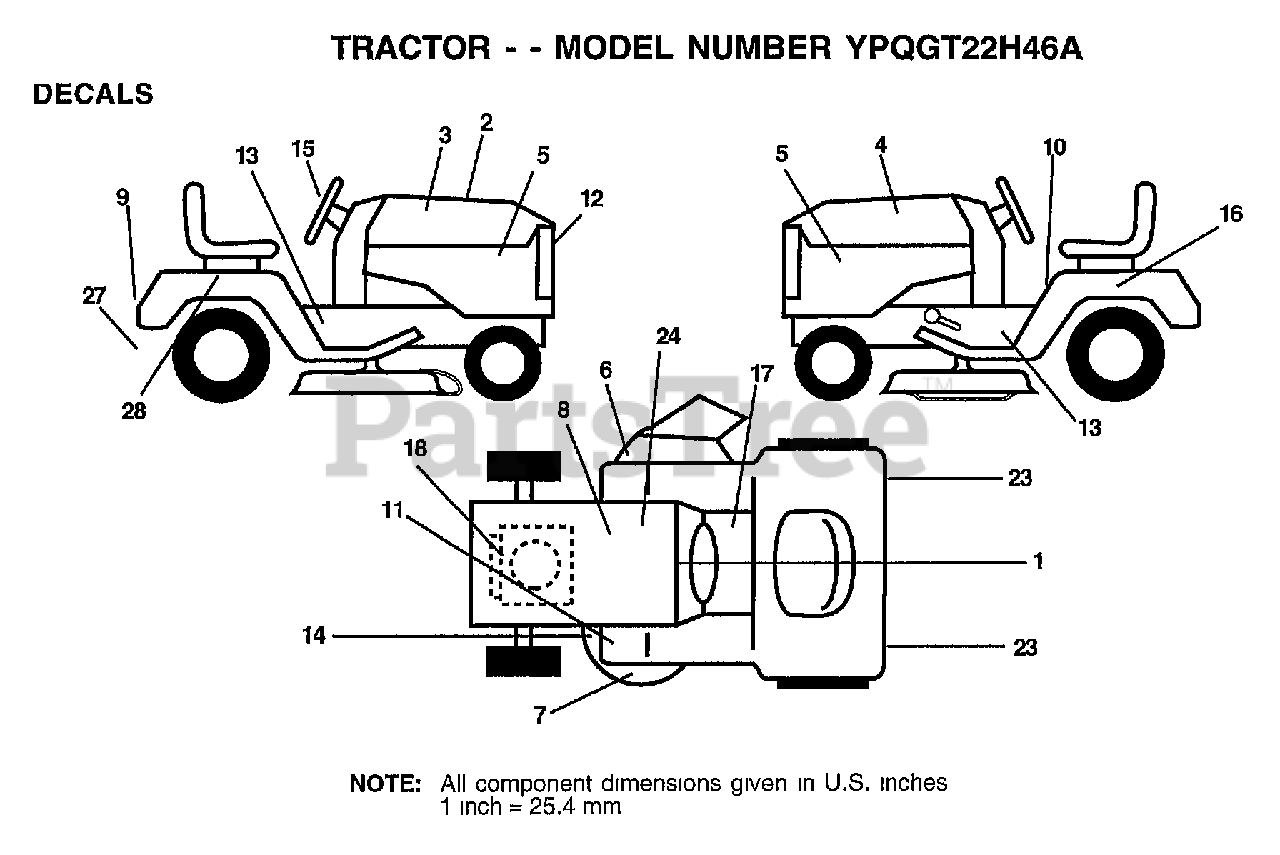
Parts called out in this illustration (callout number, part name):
1	DECAL OPER INSTR.
5	DECAL.DASH
6	"DECAL, WARNING"
7	DECAL.MOWER
9	DECAL FENDER
10	DECAL.CAUT.ENG/FR
11	DECAL T
12	DECAL GRILLE
13	"DECAL-CHASSIS,46"""
15	DECAL INS STRG WH
16	DECAL FENDER LH
17	DECAL BRAK PARK
18	DECAL/D-BAR CTRL MVT HYD YT/GT
23	REFLECTOR-TAIL YT
24	DECAL.BATRY.3-3908
27	DECAL D-BAR CNTRL
28	DECAL FENDER RH
